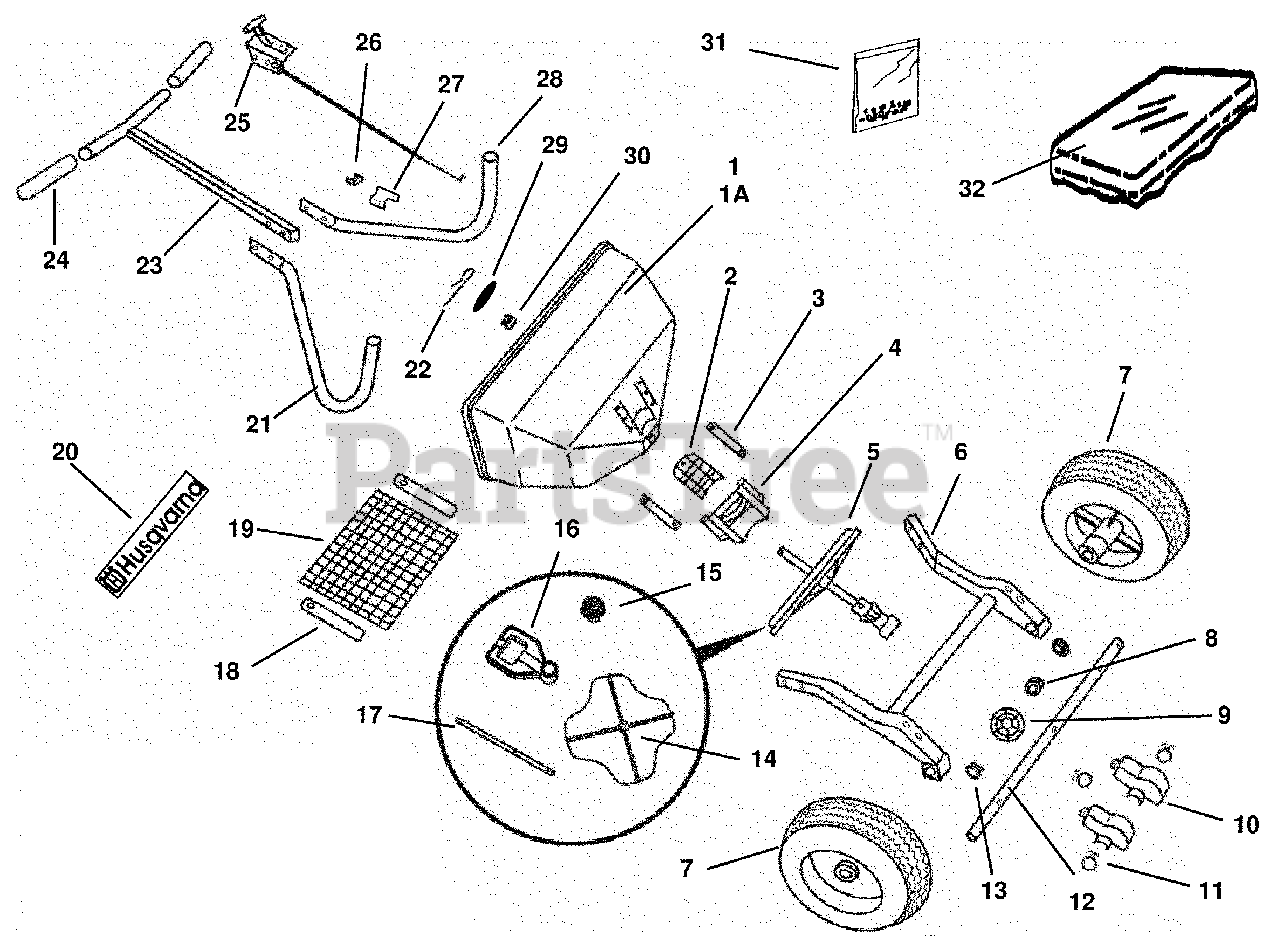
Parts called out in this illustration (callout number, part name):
1	Hopper Assembly
1A	Hopper
2	Shutoff Plate
3	Shutoff Plate Guides
4	Rate Cam & Chute Assembly
5	Impeller Assembly
6	Frame Assembly
7	Drive & Free Turning Wheel
8	Axle Collar
9	Axle Gear
10	Gear Cover Assembly (2 Req.)
11	Gear Cover Clamp (3 Req.)
12	Axle
13	Axle Bushing (2 Req.)
14	Impeller
15	Pinion Gear
16	Gear Support
17	Impeller Shaft
18	Screen Clip (2 Req.)
19	Hopper Screen
20	Hopper Label
21	Handle Brace W/ Plug– LH.
22	Agitator
23	Upper Handle Assembly
24	Handle Grip (2 Req.)
25	On/Off Control
26	Cable Clamp
27	Bracket-Cable Clamp
28	Handle Brace W/ Plug– RH.
29	Hopper Plug
30	Impeller Shaft Bearing
31	Fastener/Parts Package
32	Hopper Cover
